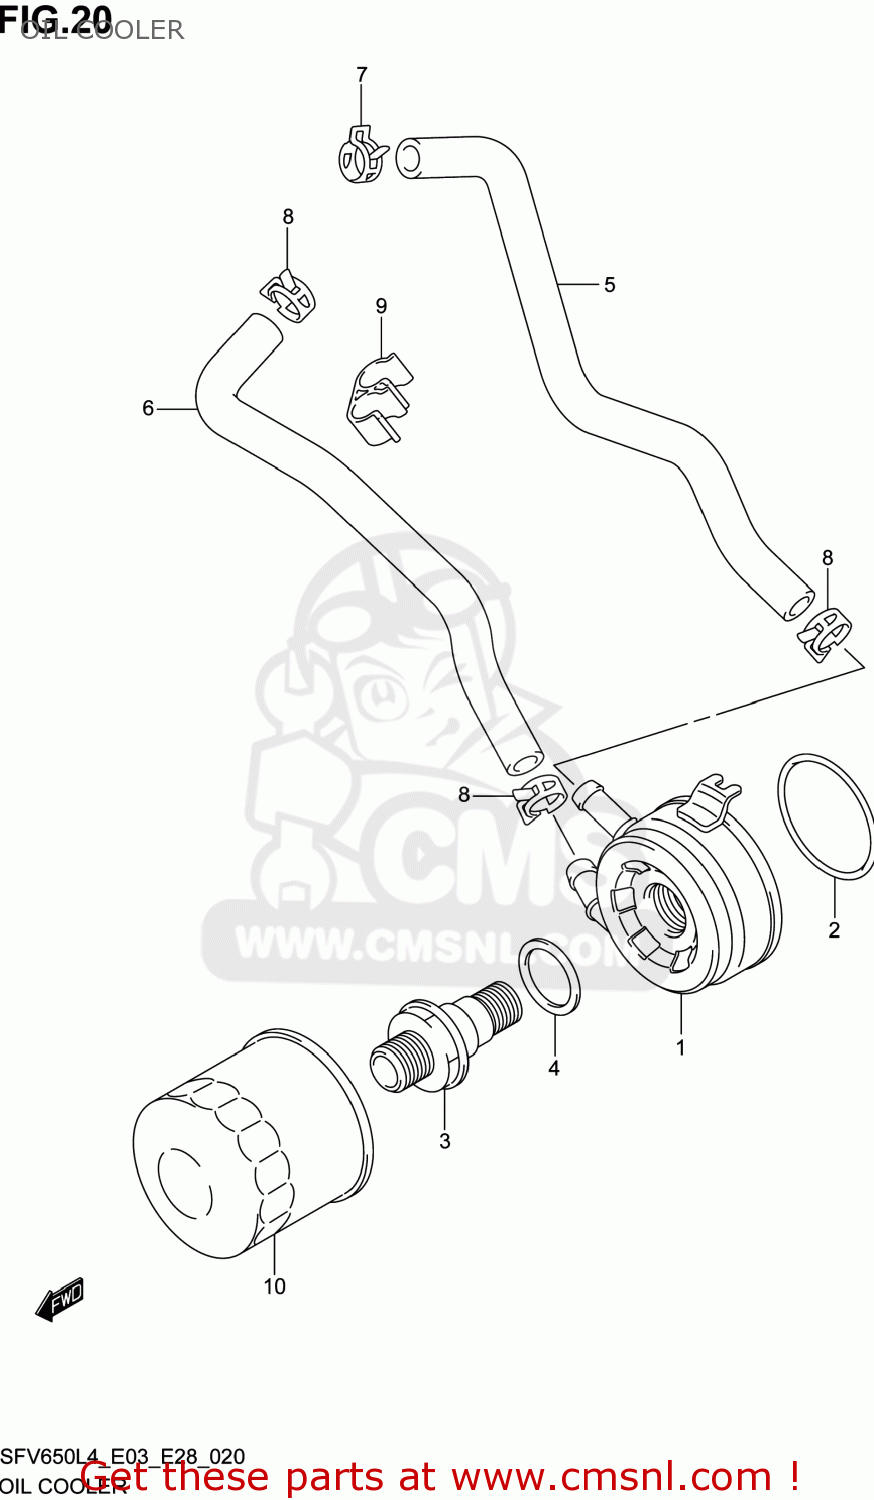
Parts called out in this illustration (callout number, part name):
1	COOLER ASSY,OIL
2	O RING(D:3.1,ID:54.5)
3	BOLT,OIL COOLER UNION
4	SHIM(25X34X0.7)
5	HOSE,OIL COOLER INLET
6	HOSE,OIL COOLER OUTLET
7	CLIP
8	CLIP
9	CLAMP
10	FILTER ASSY,ENGINE OIL
